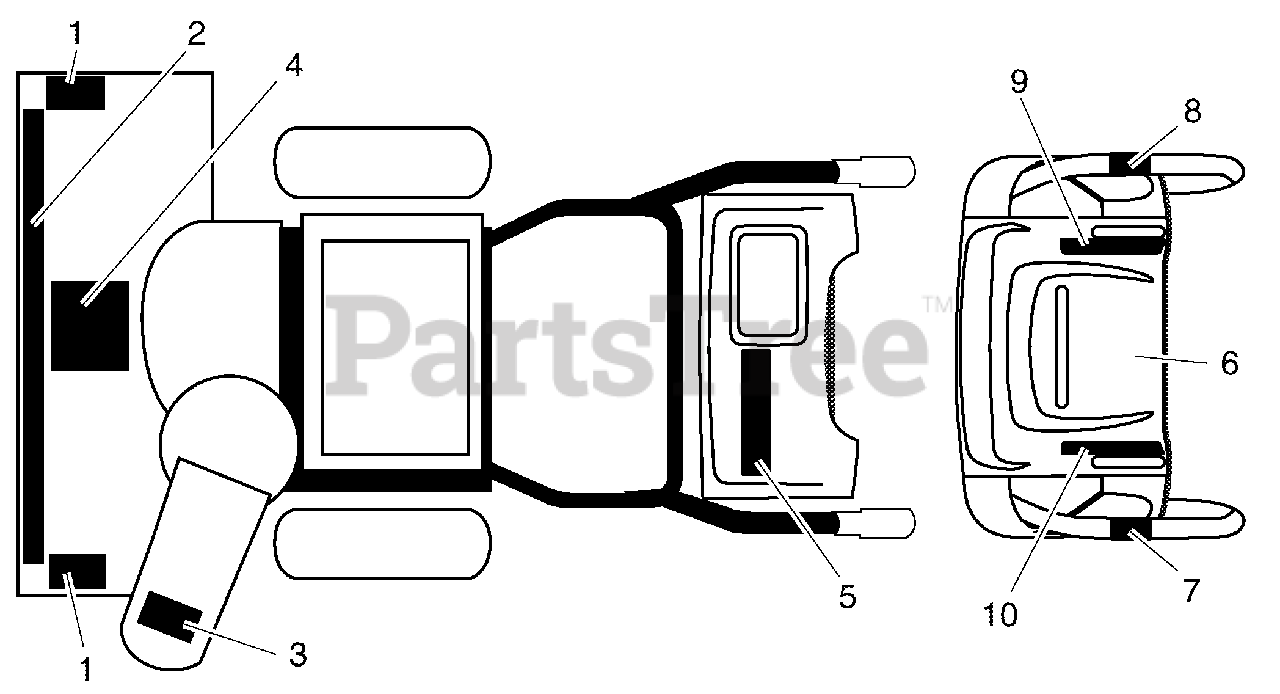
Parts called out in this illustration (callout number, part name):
1	Decal, Danger
2	Decal, Poulan Pro, 5.5HP/24"
3	Decal, Danger, Deflector
4	Decal, Danger
5	Decal, Poulan Pro
6	Decal, Instruction
7	Decal, Traction Lever
8	Decal, Auger Lever
9	Decal, Speed Control
